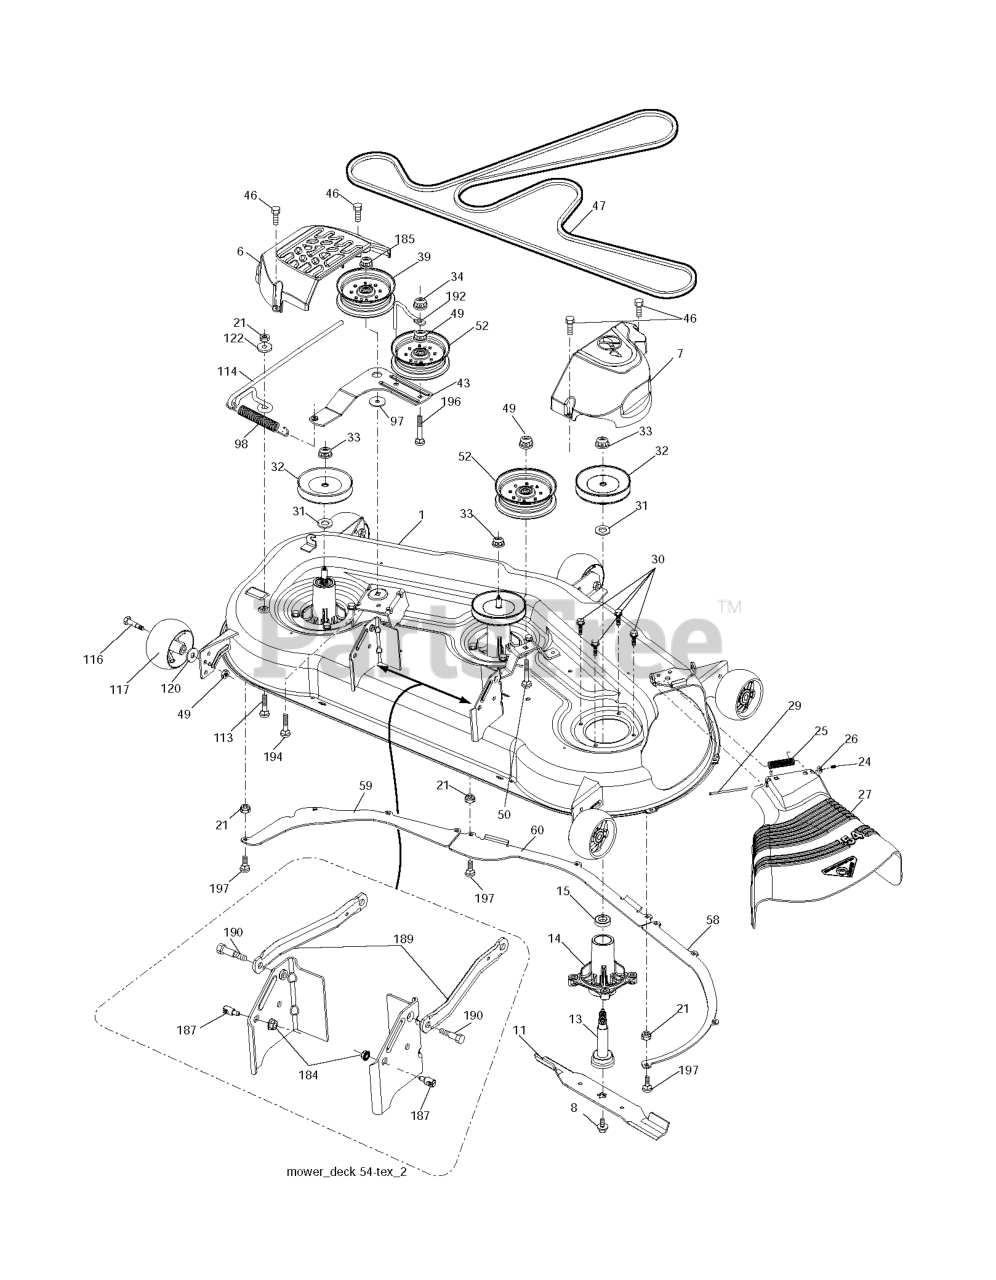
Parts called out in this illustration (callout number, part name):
1	DECK.WELDMENT.54'
6	COVER.MANDREL.LH.54"20
7	COVER.MANDREL.RH.54.20
8	BOLT 7/16 ASM BLADE
13	SHAFT ASM MANDREL
14	RP.HOUSING.MANDREL.4PT.
21	LOCKNUT
24	CAP-SLEEVE LT
25	SPRING, TORSION
26	NUT PUSH M
27	DEFLECTOR
29	ROD.HINGE
30	SCREW, WASHER HEAD
31	WASHER.SPACER.MANDREL
32	PULLEY/MANDREL
33	NUT.FLANGE.LOCK.TOP
39	RB PULLEY.IDLER.4.50/HUB SPEC
46	SCREW.1/4-20X5/8
47	RP.BELT.DRIVE.54."2006
49	NUT LOCK FLG 3/8-16 UNC
52	PULLEY.IDLER.2006
58	BAFFLE.RIGHT.54"
59	BAFFLE.LEFT.54"
60	BAFFLE CENTER 54" MOWER
98	SPRING, DECK DRIVE
114	ROD TENSION RELIEF
116	BOLT.SHOULDER.3/8-16X3-5/8.
117	RP WHEEL. GUAGE RALLY
120	WASHER
122	BUSHING.RELIEF.TENSION
184	NUT LOCK HEX FLANGE 5/16-18
185	NUT.LOCK.FLANGE.7/16
187	STUD.FASTNER.W/ANTI-ROTATE
189	ARM.SUSPENSION.MOWER
190	BOLT.SHOULDER
192	KEEPER.BELT.IDLER.54"T
194	BOLT.CARR.SQNK.7/16
